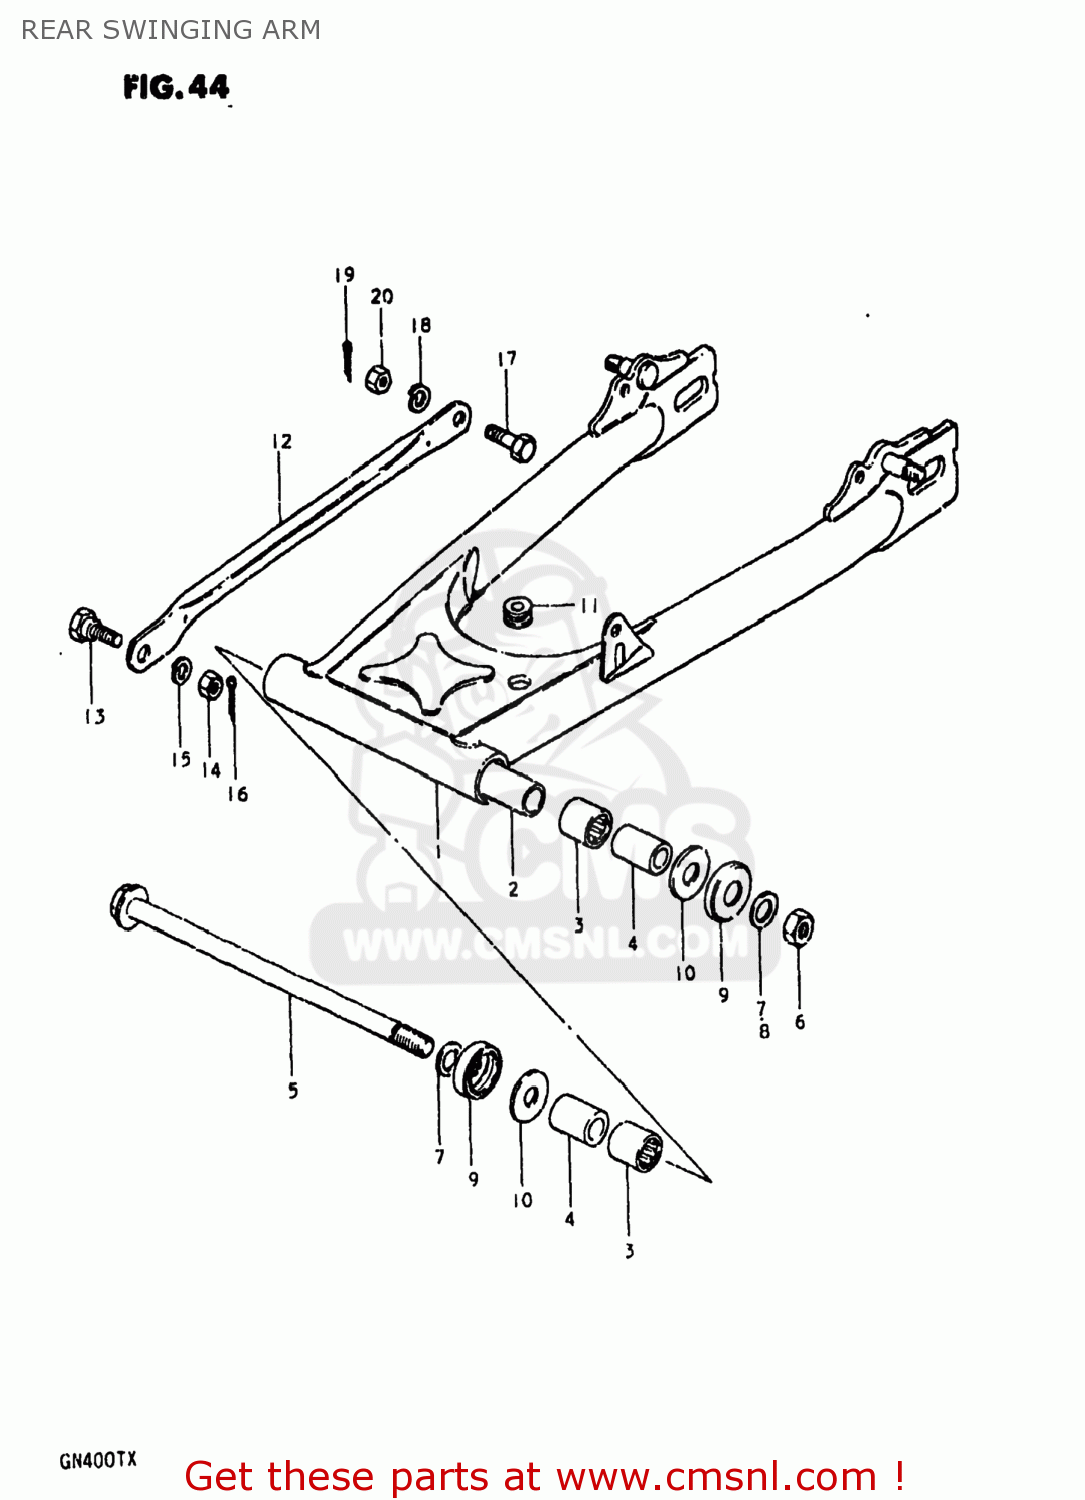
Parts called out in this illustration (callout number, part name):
1	SWING ARM ASSEMBLY,REAR
2	SPACER (16.2X21.7X129)
3	BEARING(22X29X30)
4	SPACER,REAR SWING ARM
5	SHAFT,REAR SWING ARM
6	NUT 16MM
7	WASHER
8	WASHER
9	COVER,RR SWGARM DUST SEAL
10	WASHER
11	CUSHION
12	TORQUE LINK,REAR
13	BOLT(8X22.5)
14	NUT
15	LOCK WASHER
16	PIN
17	BOLT(10X31)
18	LOCK WASHER
19	PIN
20	NUT
